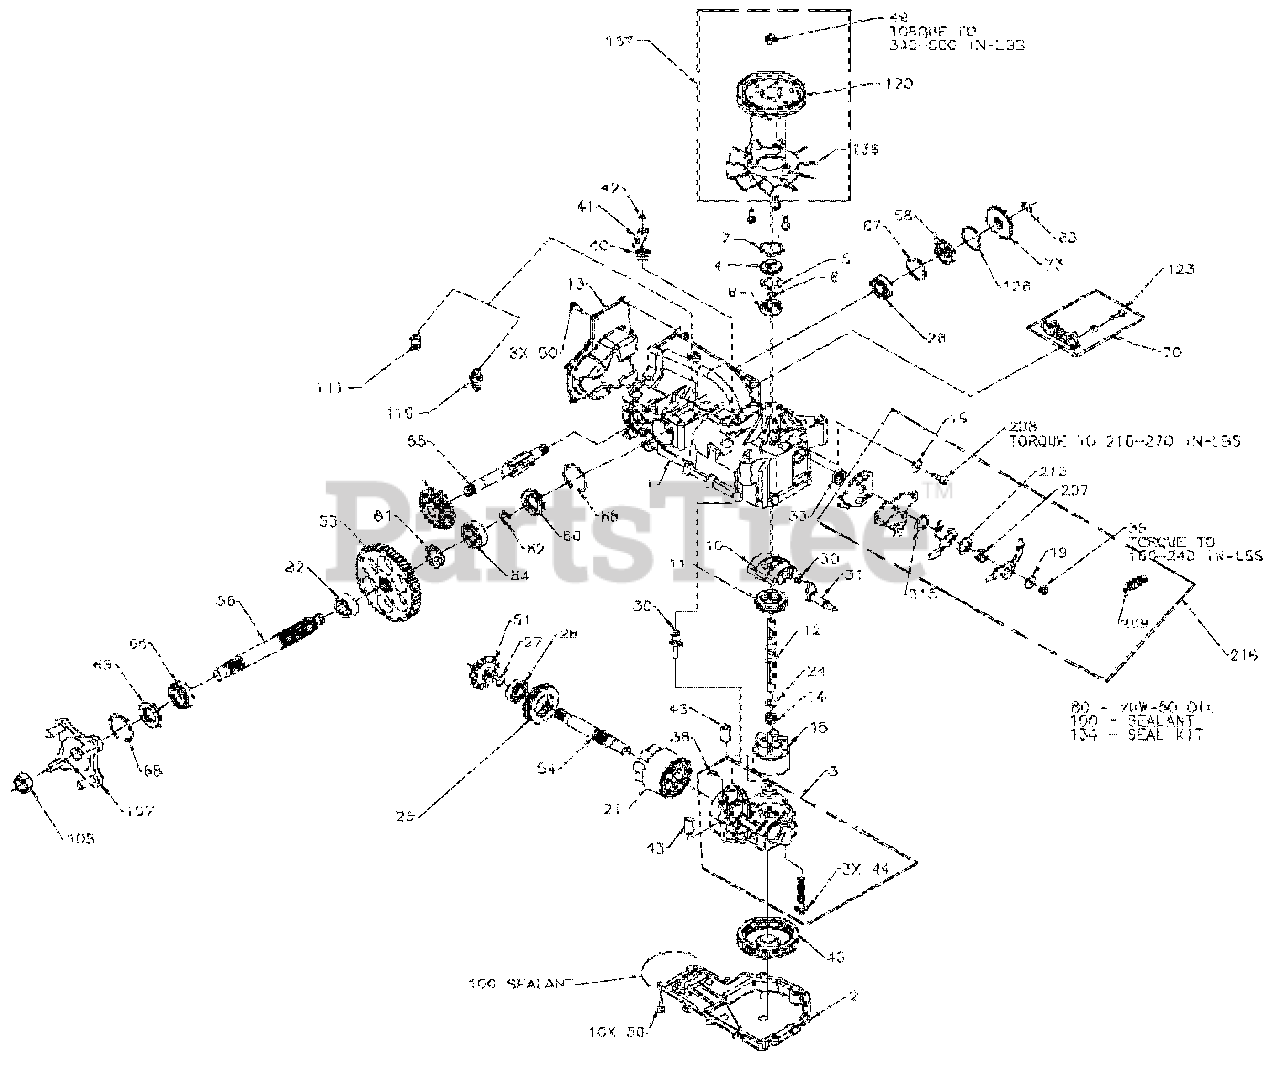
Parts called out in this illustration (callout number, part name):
1	Kit, Housing - Main
3	Kit, Center Section
4	Lip Seal
5	Spacer
6	Wire Retaining Ring
7	Retaining Ring
8	Ball Bearing
10	Variable Swashplate
11	Thrust Bearing .30 x .52 x .13
12	Input Shaft
13	Cover, Back
14	Spring, Block
18	10 cc Cylinder Block
19	Washer
21	21 cc Cylinder Block Assembly
24	Washer, Block Thrust
25	thrust Bearing .42 x .68 x .15
26	Ball Bearing
27	Wire Retaining Ring
30	Slot Guide
31	Trunnion Arm
33	Lip Seal
35	Nut
38	Kit, Bypass Plate
39	Bypass Actuator
40	Lip Seal
41	Bypass Arm
42	Retaining Ring
43	Pin
44	Screw
46	Filter
49	Nut, Hex Lock .50-20 with Nylon Insert
50	Screw, .25-20 with Nylon Insert
51	14 Teeth Bevel Gear
52	19 Teeth Bevel Gear
53	53 Teeth Spur Gear
54	Motor Shaft
55	Brake Shaft
56	Axle Shaft
57	Seal, Lip 17 x 40 x 70
60	Seal Plug - Side
62	Retaining Ring - Axle
63	Retaining Ring Kit
64	Bearing - Ball 20 x 47 x 14 (6204)
65	Bearing - Ball 25 x 47 x 12 (6005)
66	Seal
67	Retaining Ring
68	Retaining Ring - Axle
70	Brake Arm Service Assembly - Right Hand
73	Brake Disc
80	20W - 50 Oil
81	Axle Bushing
82	Axle Bushing
100	Sealant
107	Hub Assembly
108	Nut, Hex .75-16
110	Fitting, O-Ring Assembly
111	Cap Vent Assembly
120	Kit, Seal
123	Screw, Hex Washer Head .25-20 x .875
126	Retaining Ring
134	Kit, Seal
137	Kit, Fan /Pulley
207	Spacer, RTN
208	Screw, .938-24 x .75 (Patch)
209	Spring, Extension
215	Washer, Nylon
216	Kit, RTN
